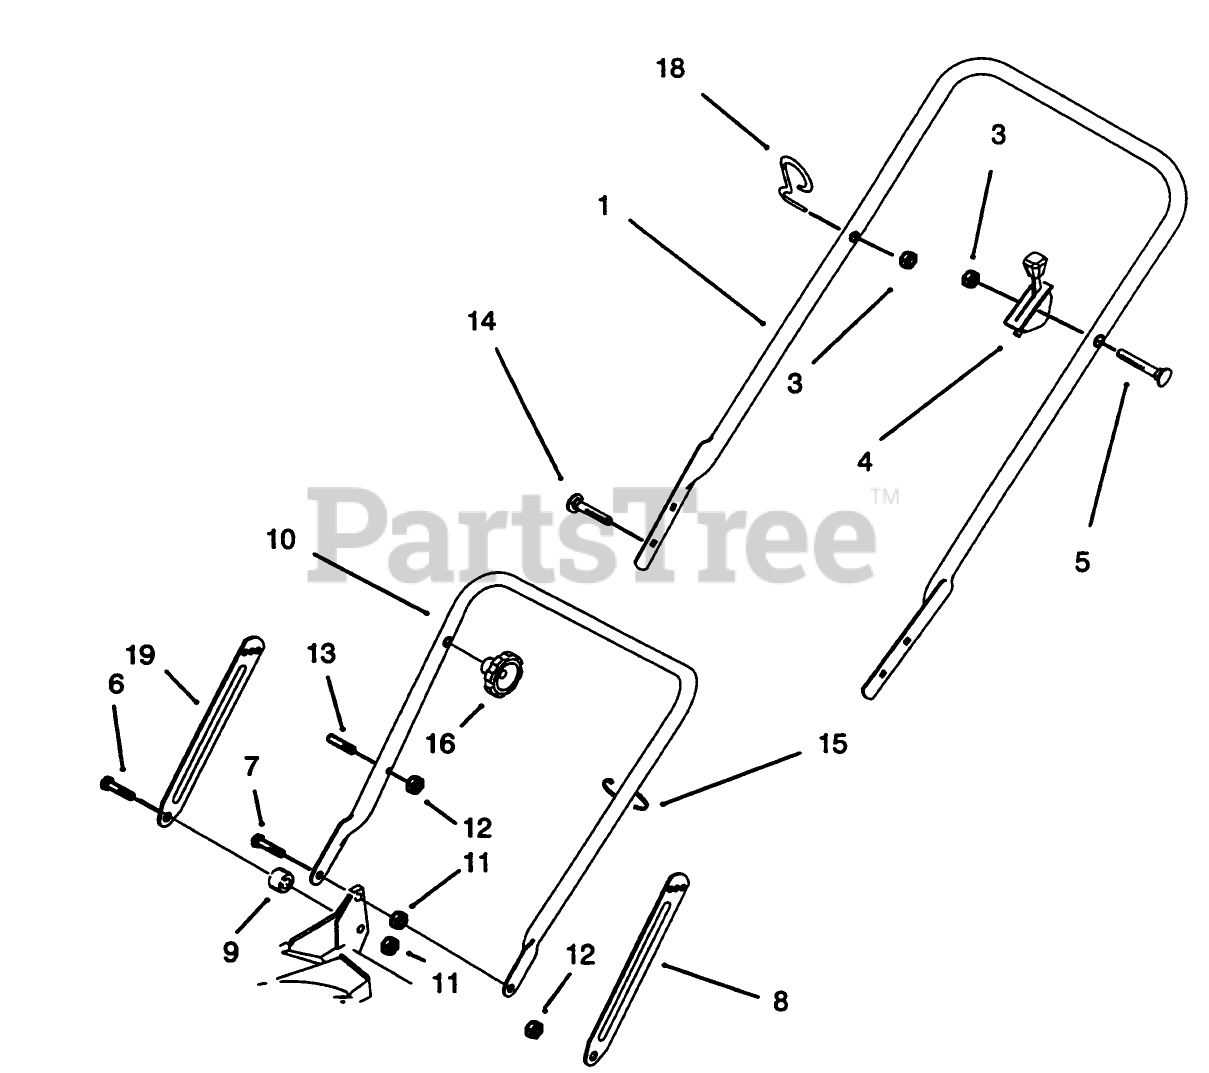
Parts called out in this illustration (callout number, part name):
3	NUT-LOCK, NI
4	THROTTLE CONTROL
5	SCREW-HANDLE
6	SCREW-SHOULDER
7	SCREW-SHOULDER
9	SPACER
11	NUT-LOCK, NI
12	NUT-LOCK, NI
13	HANDLE PIN
14	SCREW-HANDLE
15	TIE-CABLE
18	GUIDE-ROPE
